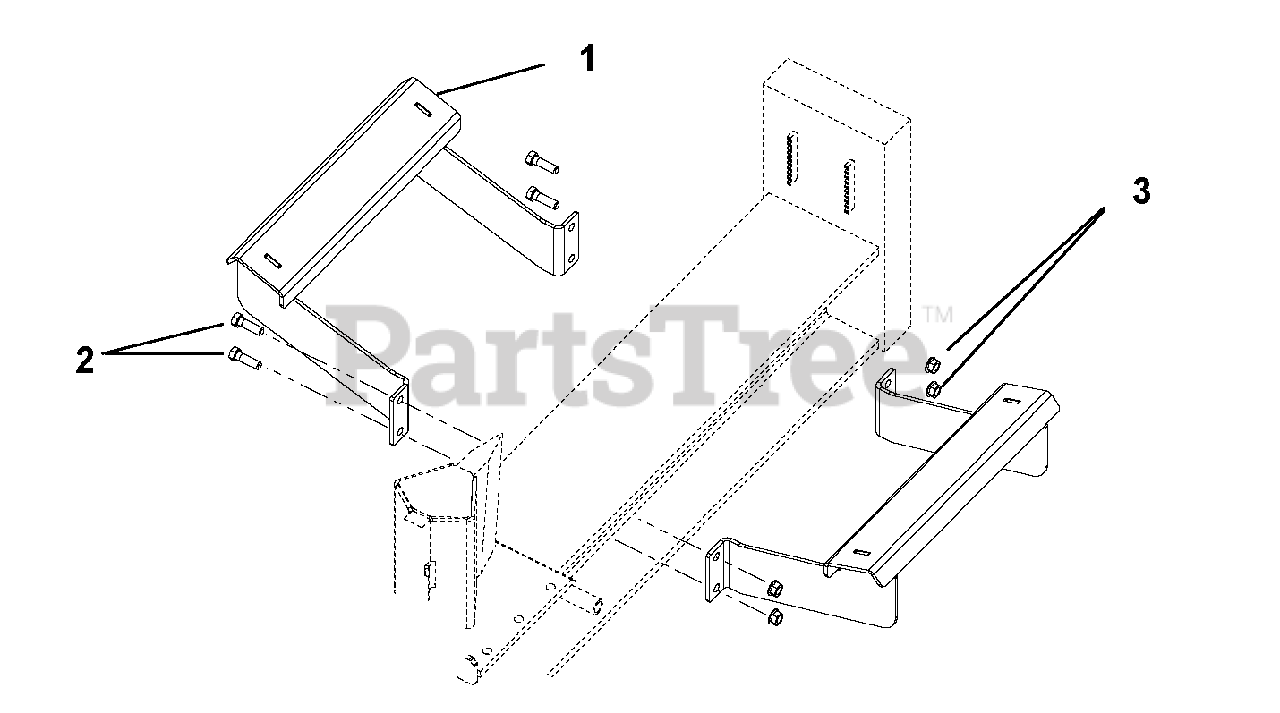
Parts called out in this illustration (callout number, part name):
1	Cradle, Log
2	Bolt, Hex .38-16x x 1.25
3	Nut, Locking Top Flange .38-16
